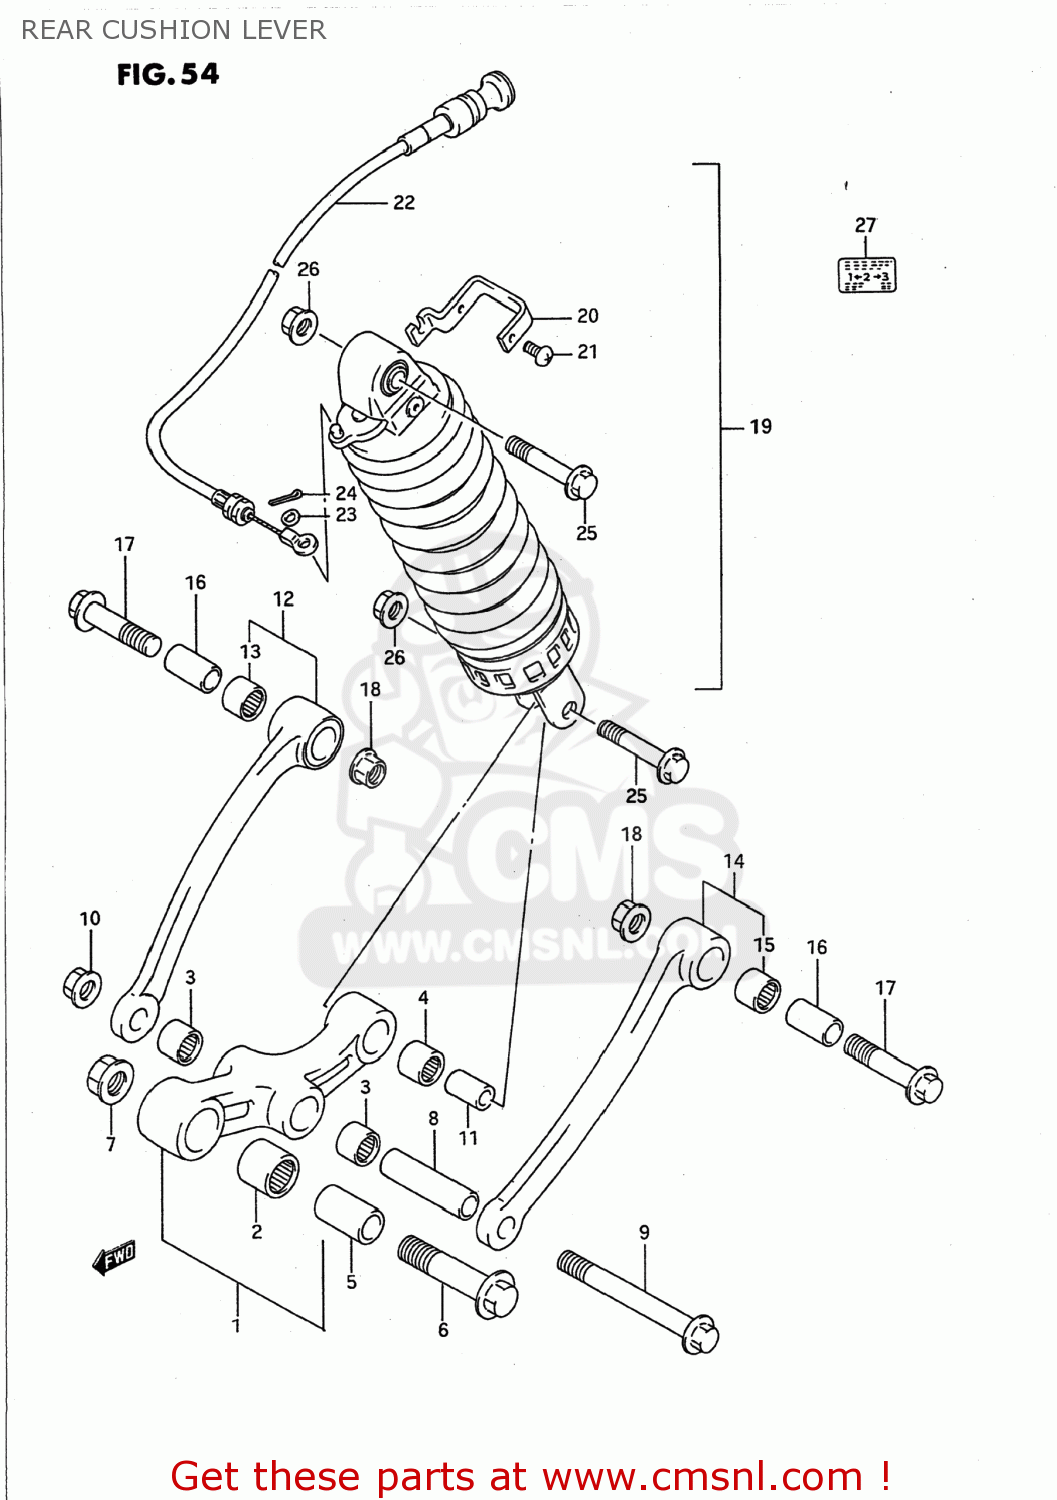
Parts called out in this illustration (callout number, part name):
1	LEVER SET,RR CUSHION
2	BEARING(20X27X30)
3	BEARING(17X24X25)
4	BEARING(17X24X26)
5	SPACER(14X20X34)
6	BOLT(14X62)
7	NUT 14MM
8	SPACER(12X17X60)
9	BOLT(12X96)
10	NUT 12MM
11	SPACER,RR CUSHION LEVER
12	ROD SET,REAR CUSHION,RIGHT
13	BEARING(17X24X26)
14	ROD SET,REAR CUSHION,LEFT
15	BEARING(17X24X26)
16	SPACER(12X17X29)
17	BOLT L:52
18	NUT 12MM
19	ABSORBER ASSY,RR SHOCK
20	CASE,GUIDE
21	SCREW
22	CABLE,CONTROL
23	WASHER
24	PIN
25	BOLT(10X52)
26	NUT 10MM
27	LABEL (REAR SHOCK ABSORBER)
